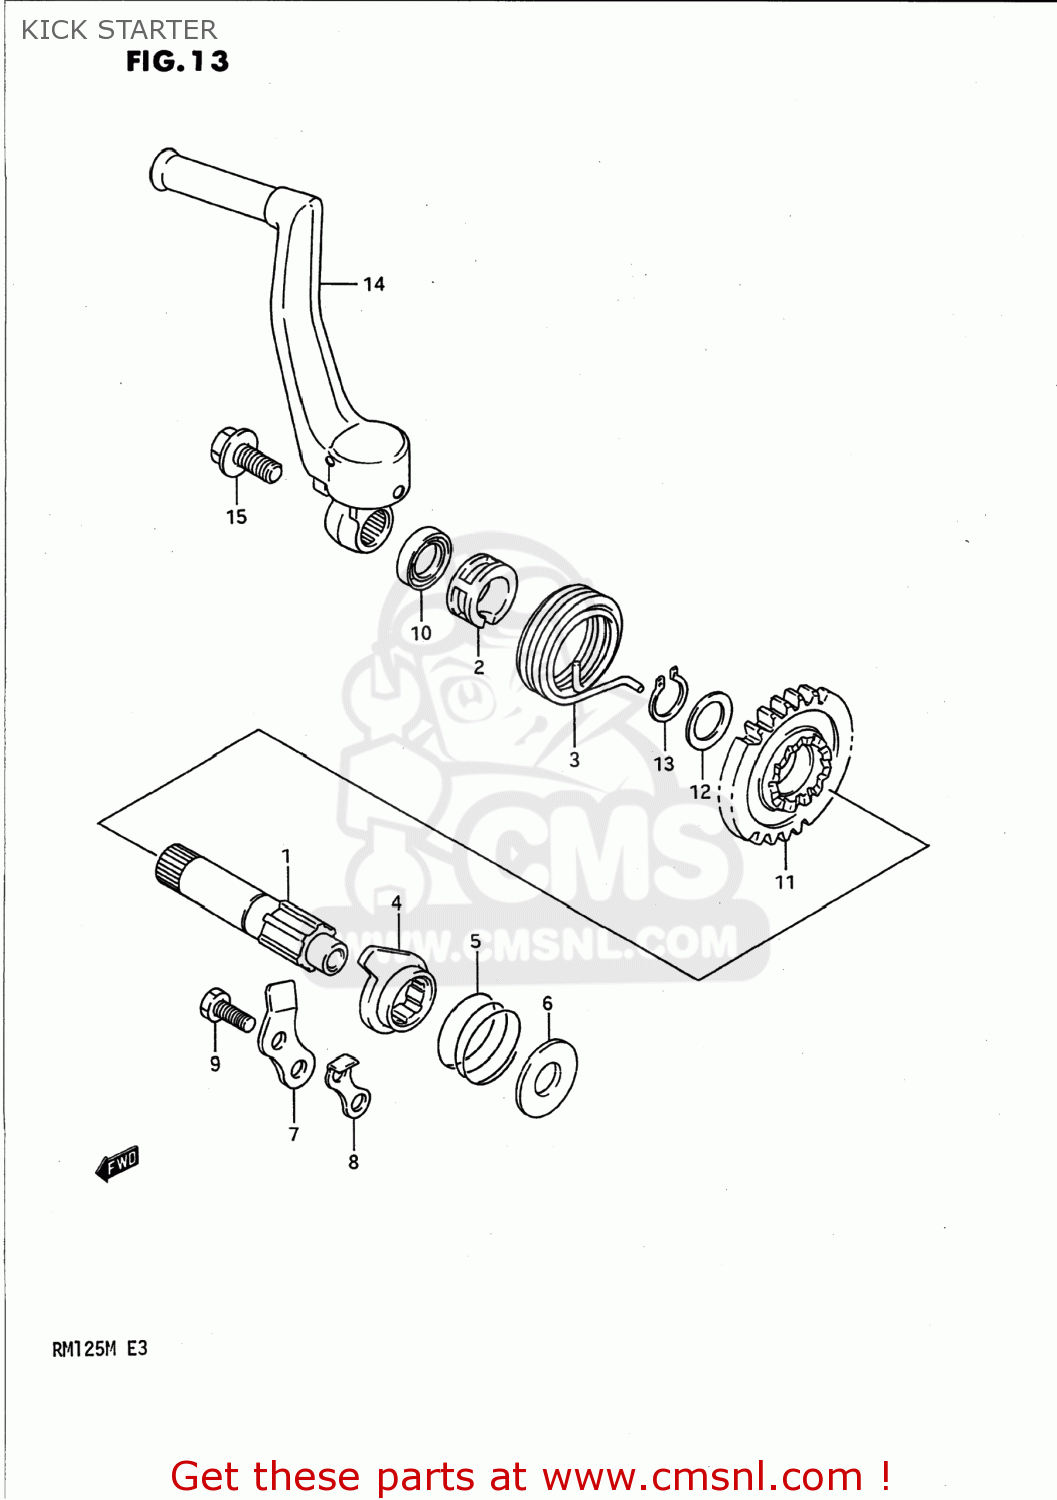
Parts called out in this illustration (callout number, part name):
1	SHAFT,KICK STARTER
2	GUIDE,KICK STARTER SFT SPRING
3	SPRING
4	STARTER,KICK
5	SPRING
6	WASHER
7	GUIDE,KICK STARTER
8	STOPPER,KICK STARTER
9	BOLT
10	SEAL,OIL(16X24X5)
11	GEAR,KICK STARTER DRIVE
12	WASHER
13	CIRCLIP,16MM
14	LEVER ASSEMBLY,KICK STARTER
15	BOLT(8X14)
